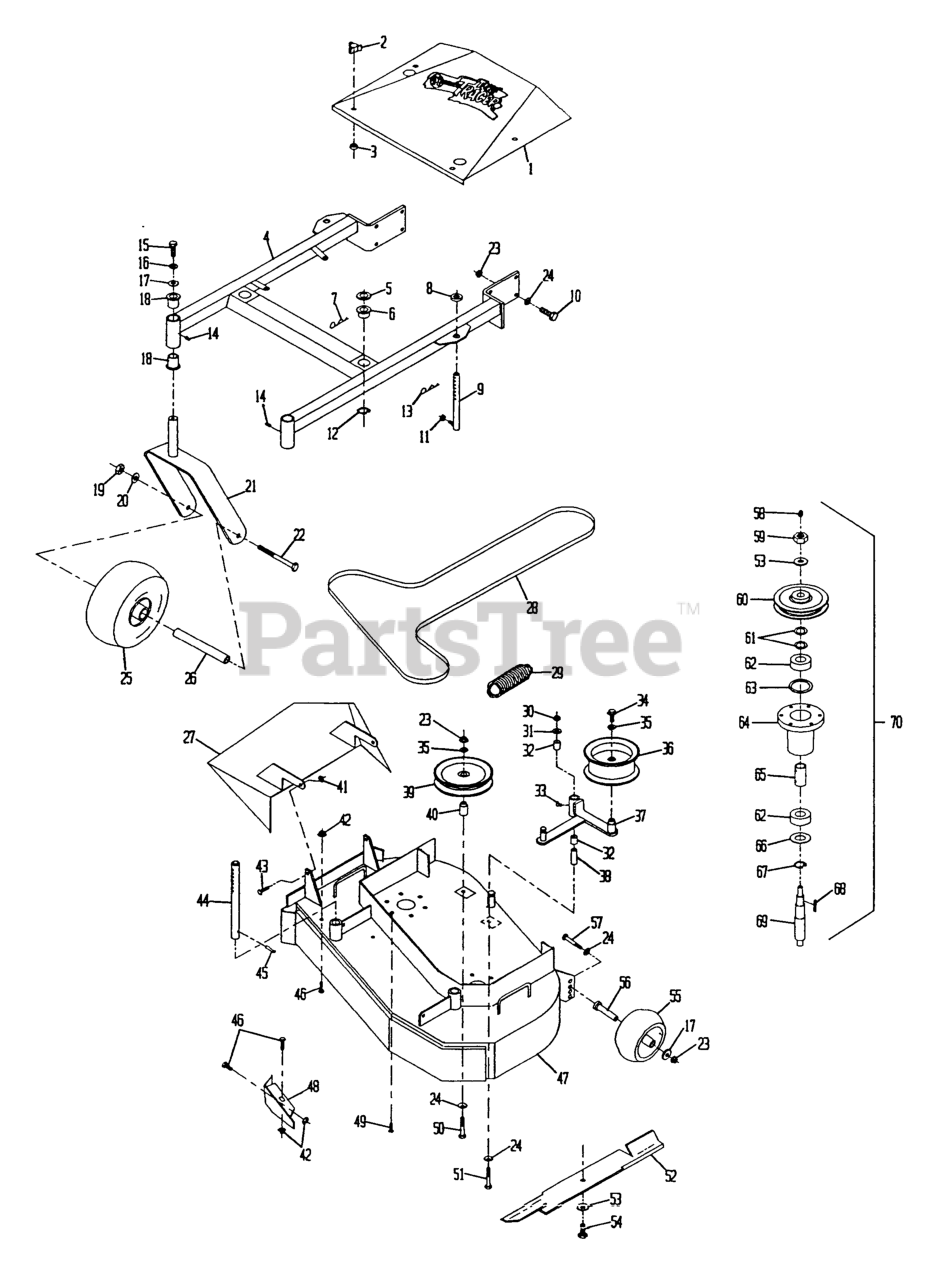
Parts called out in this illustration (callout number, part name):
2	KNOB-3 PRONG
4	DECK SUPPORT W/BSHGS 36"
5	WASHER-FLAT
6	BUSHING-DECK
13	PIN,HAIR COTTER
18	BEARING-FLANGED
28	BELT,DECK DRIVE
32	SLEEVE-BEARING
38	BUSHING-PIVOT, IDLER
39	PULLEY-IDLER
40	BUSHING-IDLER
44	ROD,DECK SUPPORT
47	ASM,DECK W/DECALS TTHP/MH
49	SCRW,TPTTE HH
51	SCREW-HH
53	WASHER-SPRING
55	ROLLER-SCALP, ANTI
56	BUSHING-ROLLER
60	SHEAVE,W/HUB 5.72
61	WASHER-SPACER
62	BEARING,HD SPINDLE
64	HOUSING,BEARING
65	SPACER,BEARING
66	SEAL,MECHANICAL DUST
67	RING,SNAP WLDS N5000-244
68	KEY-RECTANGLE
